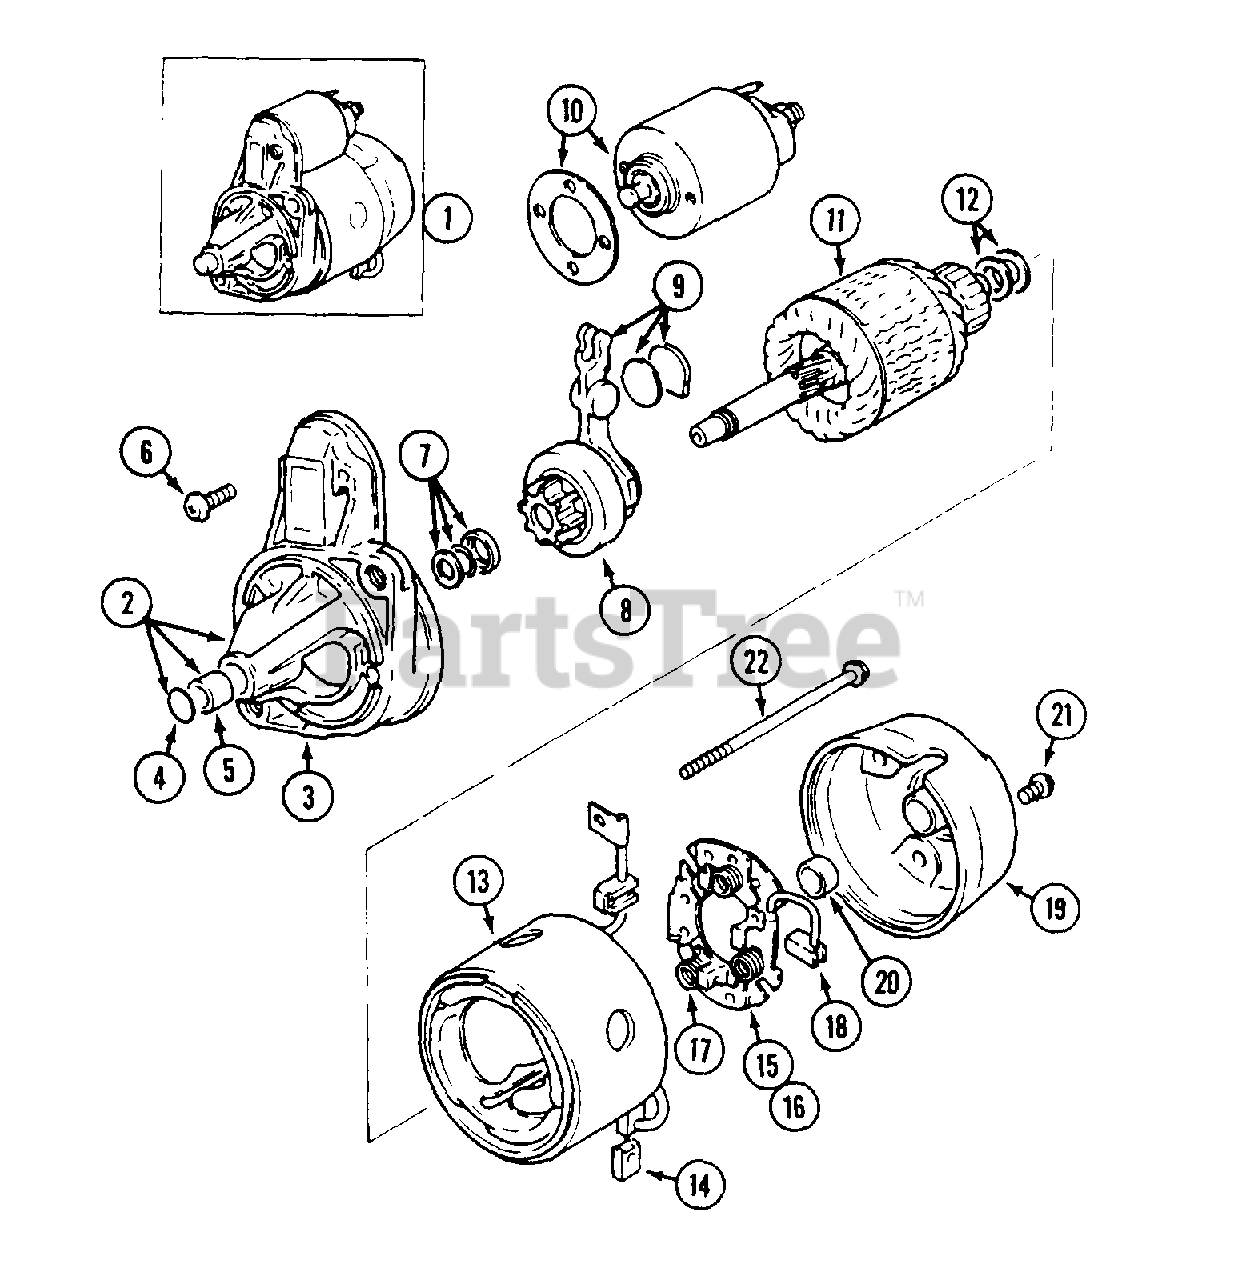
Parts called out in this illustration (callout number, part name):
1	STARTER
2	COVER ASSEMBLY
3	COVER
4	RING
5	BUSHING
6	SCREW
7	WASHER
8	PINION
9	LEVER
10	SWITCH
11	ARMATURE
12	WASHER
13	YOKE
14	BRUSH
15	HOLDER ASSEMBLY
16	HOLDER
17	SPRING
18	BRUSH
19	COVER
20	BUSHING
21	SCREW
22	SCREW
